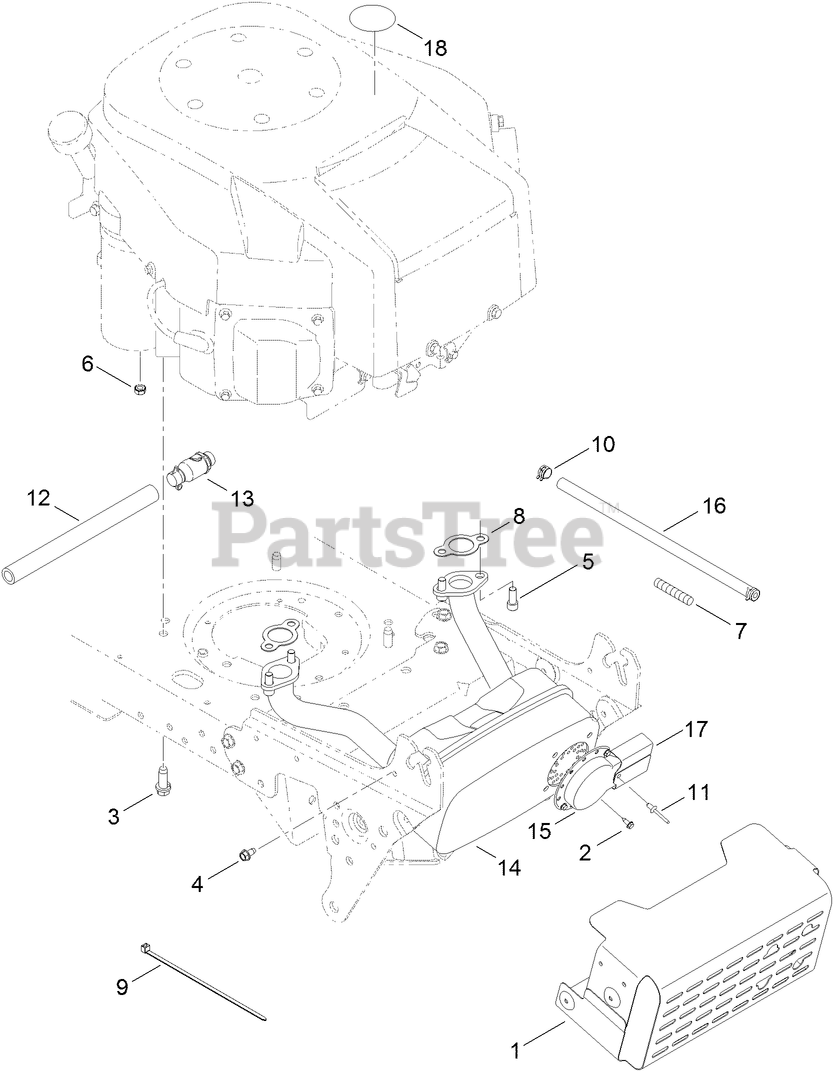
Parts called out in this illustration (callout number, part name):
1	SHIELD-MUFFLER
2	SCREW-HWHTF
3	SCREW-HH, TAP
4	SCREW-HWHTF
5	SCREW-HSH
6	NUT-SEMS
7	HOSE-VENT
8	GASKET-EXHAUST
9	TIE-CABLE
10	CLAMP-HOSE
11	RIVET-POP
12	HOSE-DRAIN
13	DRAIN-OIL
14	MUFFLER-TWIN
15	DEFLECTOR-MUFFLER
16	HOSE-FUEL
17	DEFLECTOR-MUFFLER
18	DECAL-CHECK OIL
